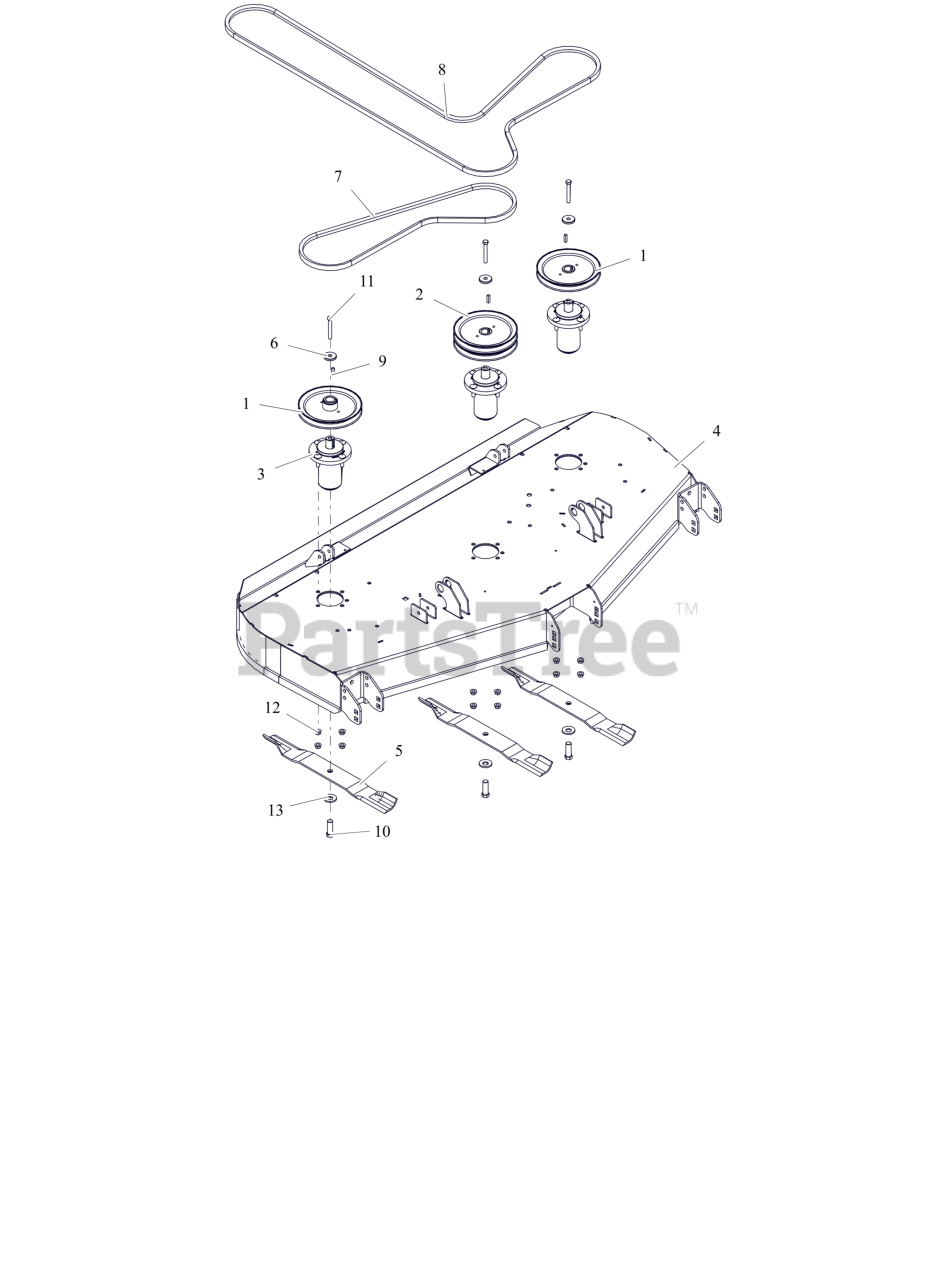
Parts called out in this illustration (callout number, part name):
1	PULLEY, V-7.50 OD X 1"ID
2	PULLEY, DOUBLE 1"X7.50"&7.50" (BLACK)
3	ASM, MAINT FREE ALUM SPINDLE
4	WLDMT, 60" SIDE DISCH DECK CE
5	BLADE, 20.5"
6	RETAINER, SHEAVE
7	V-BELT, B-COGGED
8	V-BELT, HB SECTION
9	KEY, SQ .25X.25X1.00 RC 40-50
10	BLT, HEX .62-18X1.75 G8 ZCC
11	BLT, HEX .38-16X2.75 G8 ZCC
12	NUT-LK-CTR-FLG .375-16 GF ZCC
13	WSHR-BLVL .669X1.535X.138
